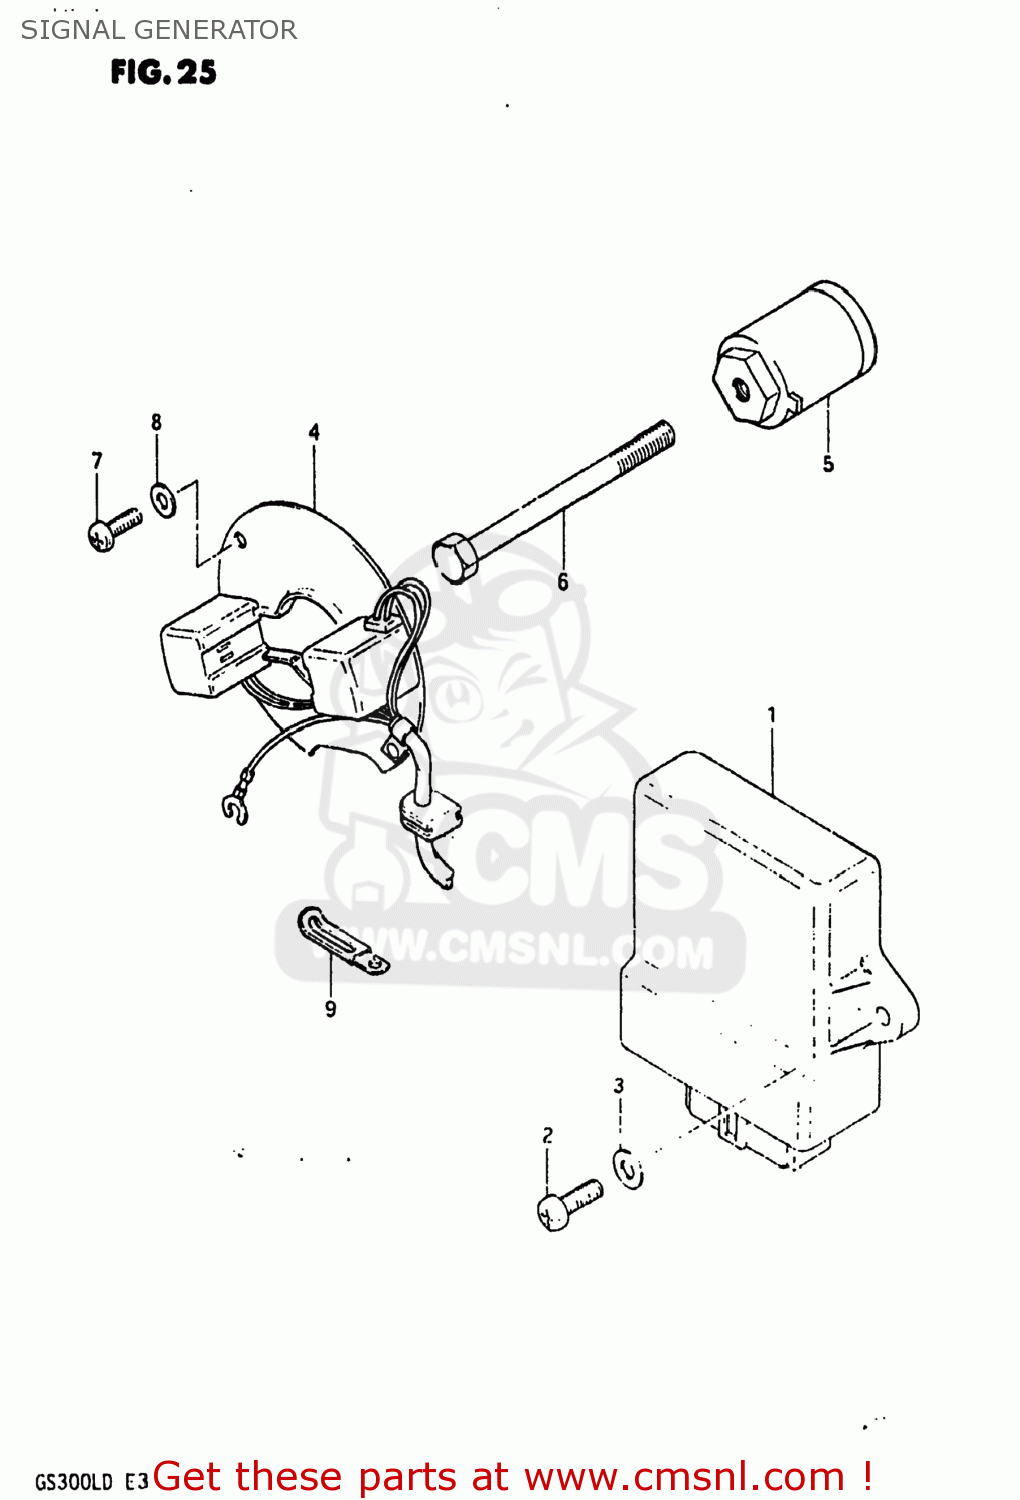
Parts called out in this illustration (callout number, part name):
1	IGNITER UNIT ASSEMBLY
2	SCREW
3	WASHER
4	SIGNAL GENERATOR ASSEMBLY
5	ROTOR,SIGNAL
6	BOLT
7	SCREW(5X12)
8	WASHER
9	CLAMP L:35
